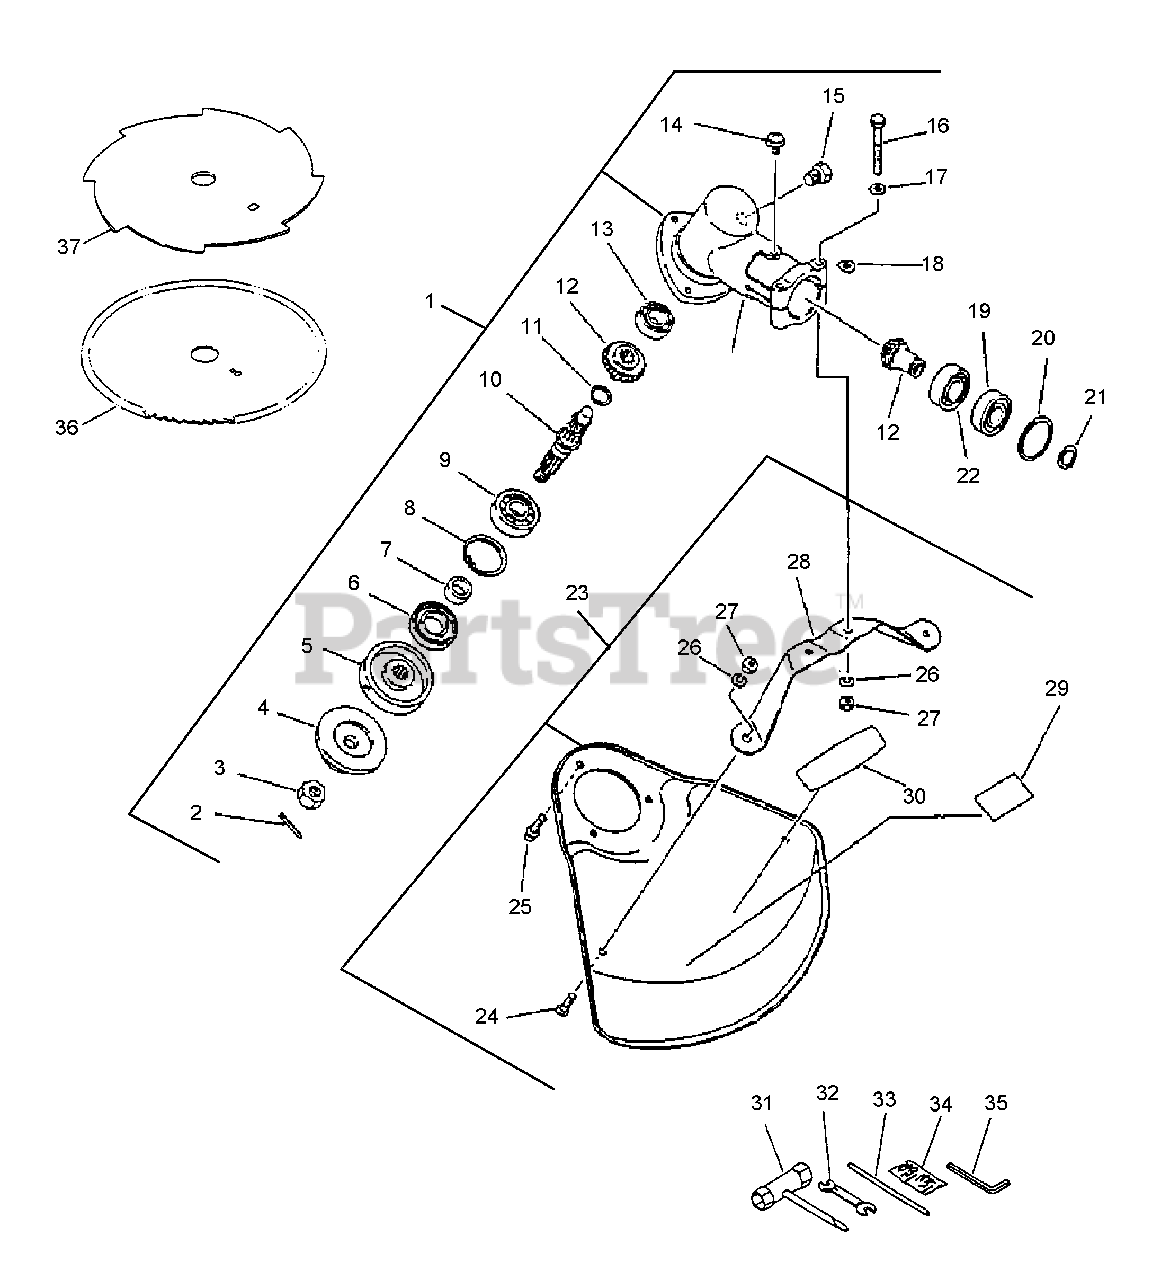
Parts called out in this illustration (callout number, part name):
1	GEAR CASE ASSY
2	PIN, COTTER 2×22
4	PLATE, ADAPTOR - LOWER
5	PLATE, ADAPTER - UPPER
6	SEAL, OIL 22
7	SPACER 11.8×15×9
8	RING, SNAP Ø32
9	BEARING, BALL - 6201 C3
10	SHAFT, GEAR
11	RING, SNAP Ø12
12	GEAR SET
13	BEARING, BALL 6000
14	SCREW 5×10
15	BOLT 8×8 SP
16	BOLT 5×40
17	WASHER, FLAT 5.5×10×0.8
19	BEARING, BALL 6001
20	RING, SNAP 28
21	RING, RETAINING - 12
22	BEARING, BALL 6001
23	DEBRIS SHIELD KIT - BLADE
24	SCREW 5×8
25	SCREW 5×10
26	WASHER, SPRING 5
27	NUT M5
28	BRACKET, SHIELD MOUNTING
29	LABEL, DANGER
30	LABEL, ECHO
31	T-WRENCH 17x-19 L200
32	SPANNER 8×10
33	TOOL, LOCKING 5×120 MM
34	PIN, COTTER 2×22 (PKG. OF 10)
35	WRENCH, ALLEN 4 MM
36	BLADE, 10" 80 TOOTH
37	BLADE 8" - 8 TOOTH (25 MM ARBOR)
